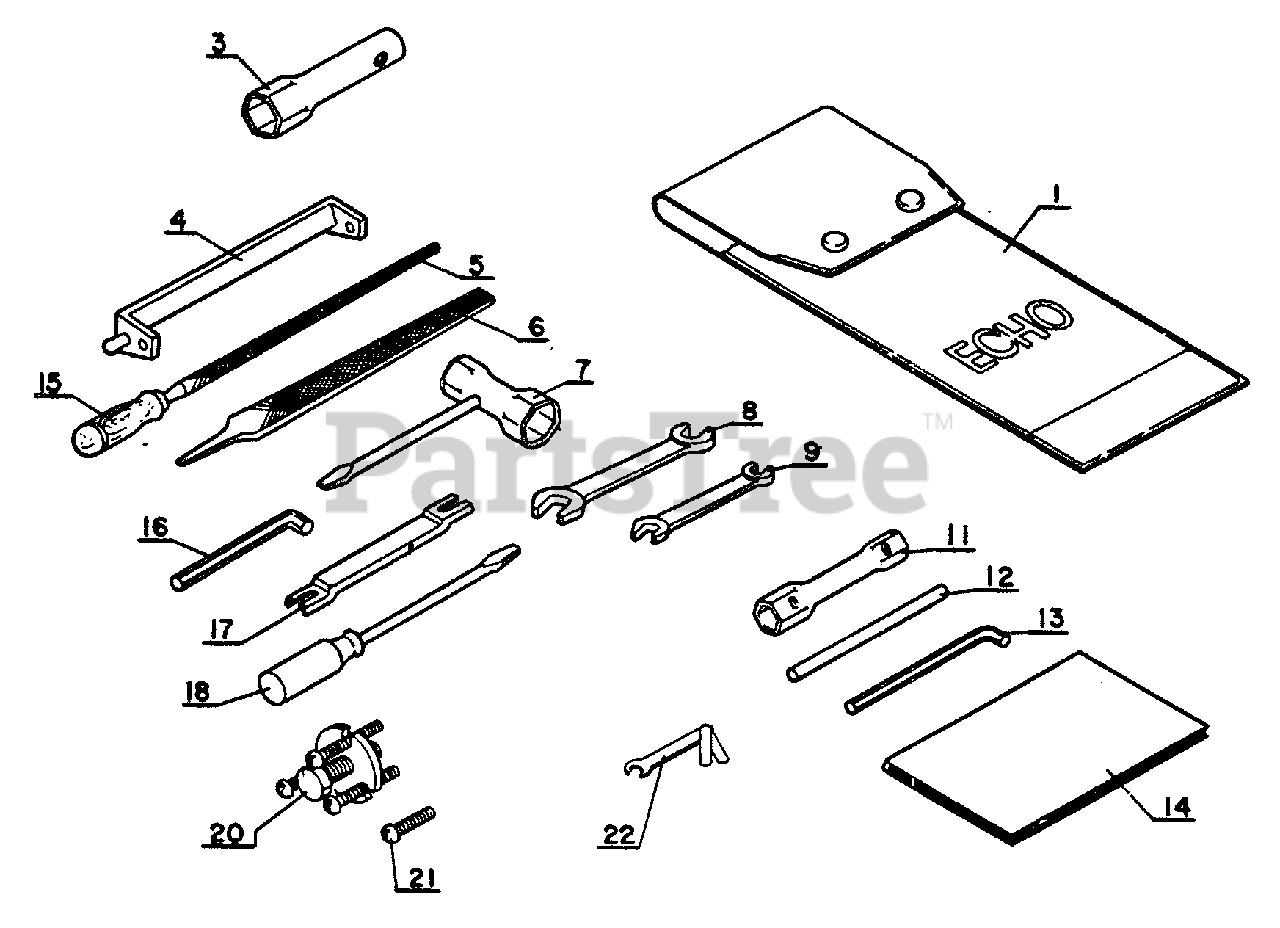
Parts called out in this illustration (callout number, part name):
1	BAG, TOOL
3	SOCKET WRENCH - 17mm
4	File holder
5	FILE - ROUND
6	FILE - FLAT
7	T-WRENCH - 13X19mm
8	SPANNER - 10X13mm
9	SPANNER - 8X9mm
11	SOCKET WRENCH - 8X10mm
12	ROD, HANDLE
13	HEX KEY - 4mm
14	Instruction manual
15	FILE GRIP
16	HEX KEY - 5mm
17	DEPTH GAUGE
18	SCREWDRIVER
20	PULLER
22	Magneto spanner
27	SCREWDRIVER - (+)
